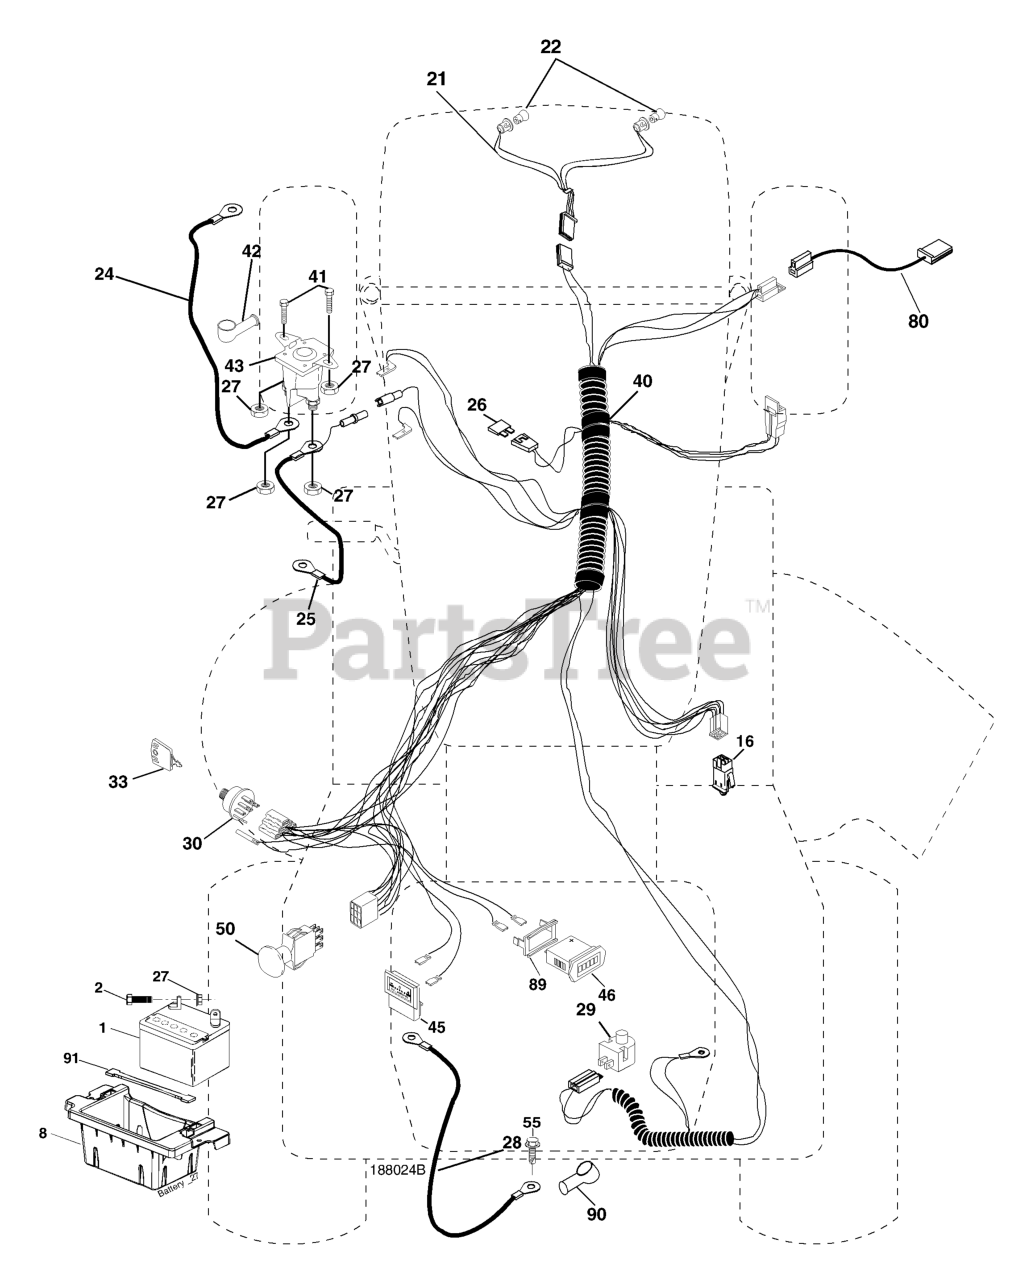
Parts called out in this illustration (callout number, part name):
1	BATTERY 12V .35 AMP
2	BOLT.HEX.1/4.X.3/4.DICHROMATE
8	BOX.BATTERY.MOUNT.FRONT.LT
16	SWITCH INTERLOOK PUSH-IN
21	HARNESS ASSY LIGHT
24	CABLE BATTERY 6 GA 22" W/16W
25	BATTERY CABLE GT
26	FUSE 20AMP
27	NUT
28	CABLE GROUND 6 GA 21" 90T BLK
29	RP.SWITCH.PLUNGER.NC.GRAY
30	IGNITION SWITCH
33	KEY MLD GEN DELTA
40	HARNESS.IGNITION
41	BOLT
42	TERMINAL COVER
43	SOLENOID
46	HOUR METER
50	RP.PTO.SWITCH.8 TERMINAL.BLACK
55	Screw Thdrol 5/16-18 x 1-1/2 Tyt
80	HARNESS, CLUTCH
89	BRACKET SNAP-IN HOURMETER
90	COVER TERMINAL
91	STRAP.BATTERY.MOUNT.FRONT(2 2)
